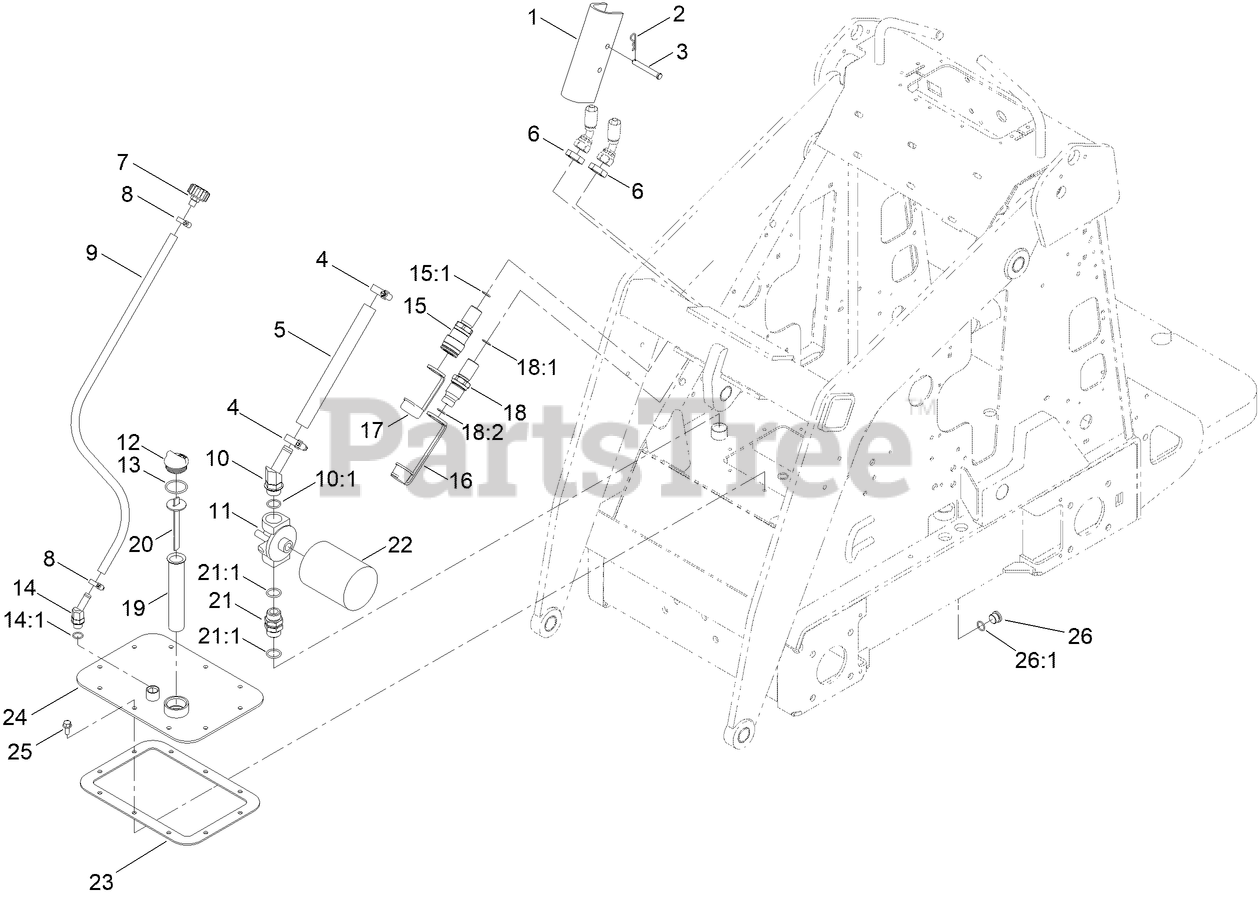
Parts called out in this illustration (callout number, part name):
1	LOCK-CYLINDER
2	PIN-HAIR
3	PIN-CLEVIS
4	CLAMP-HOSE
5	HOSE-HYD, SUCTION, HI
6	NUT-LOCK, BULKHEAD
7	BREATHER
8	CLAMP-HOSE
9	HOSE-VENT
10	FITTING-ELBOW45
10:1	O-RING
11	HEAD-FILTER
12	PLUG-PLASTIC
13	O-RING
14	FITTING-ELBOW, 45
14:1	O-RING
15	BULKHEAD COUPLER ASM
15:1	O-RING
16	CAP-DUST, NIPPLE
17	CAP-DUST, COUPLER
18	BULKHEAD NIPPLE ASM
18:1	O-RING
19	FILTER-SCREEN
20	DIPSTICK-OIL
21	FITTING-THREAD, STRAIGHT
21:1	O-RING
22	FILTER-OIL, TRANSMISSION
23	GASKET-COVER
25	SCREW-HHF
26	PLUG-HEX
26:1	O-RING
